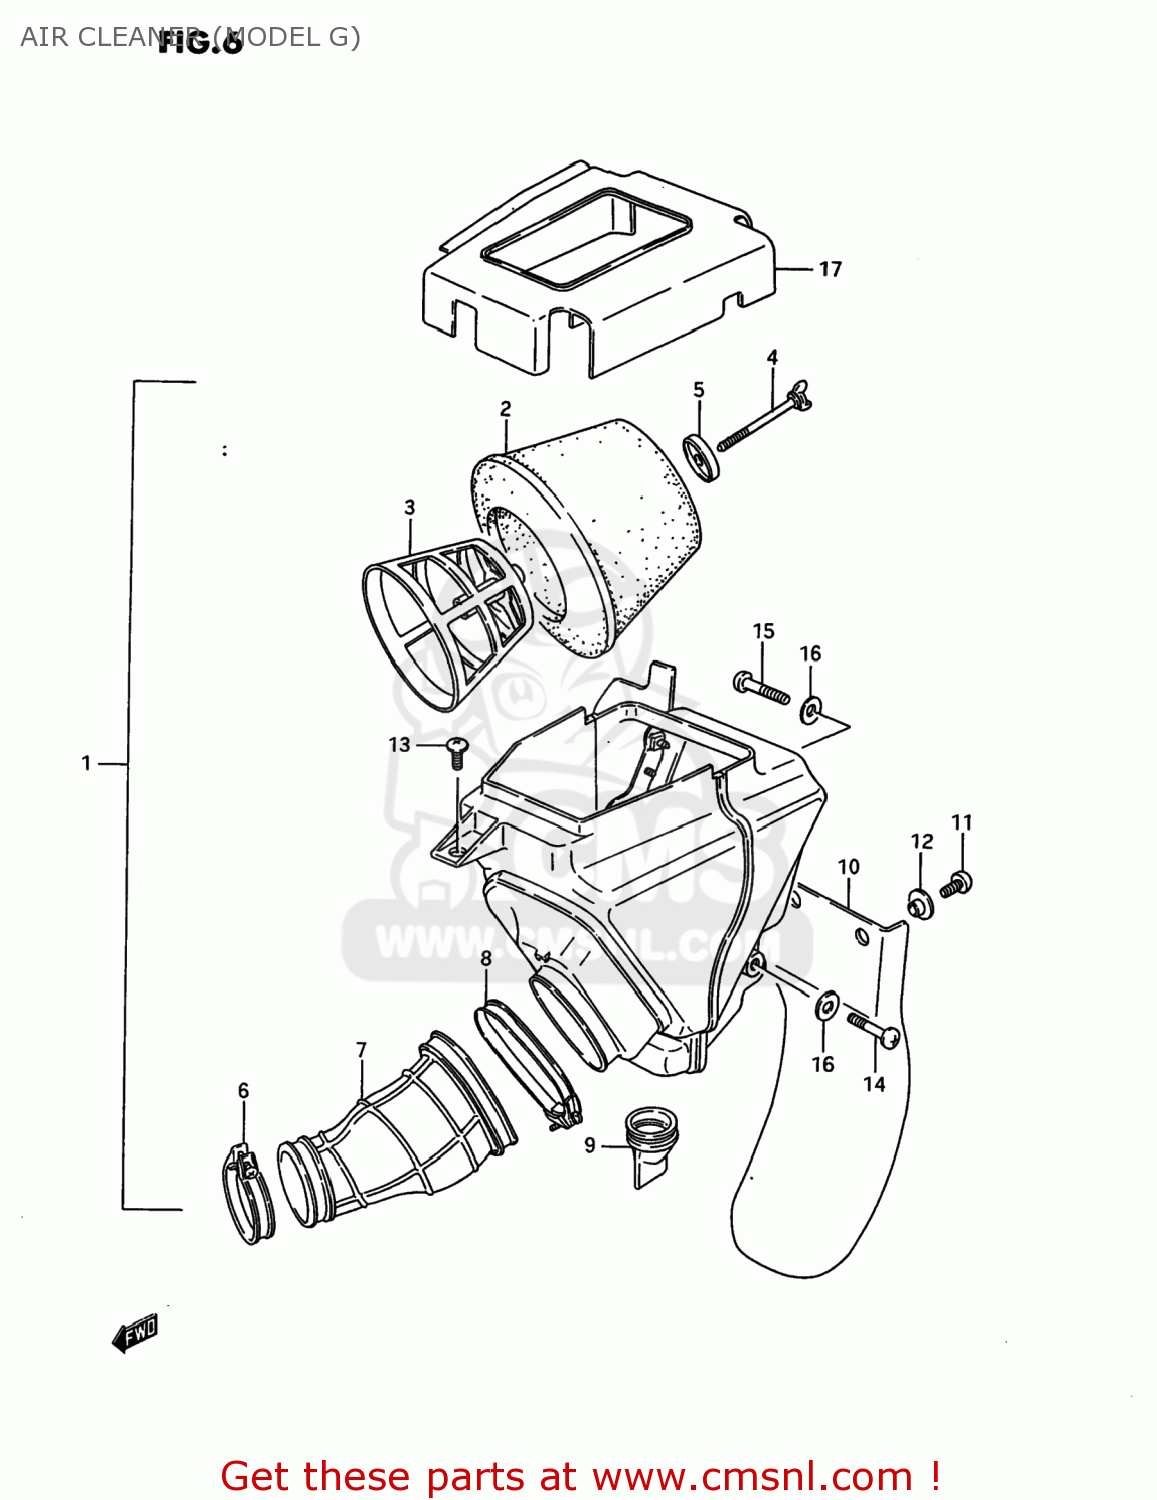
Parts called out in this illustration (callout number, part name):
1	CLEANER ASSEMBLY,AIR
2	FILTER ASSY
3	HOLDER
4	BOLT,WING
5	WASHER,AIR CLEANER
6	CLAMP
7	TUBE,AIR CLEANER OUTLET
8	CLAMP
9	HOSE,AIR CLEANER DRAIN
10	GUARD,MUD
11	SCREW
12	COLLAR
13	SCREW 6X12
14	SCREW
15	SCREW
16	WASHER
17	GUARD,MUD
